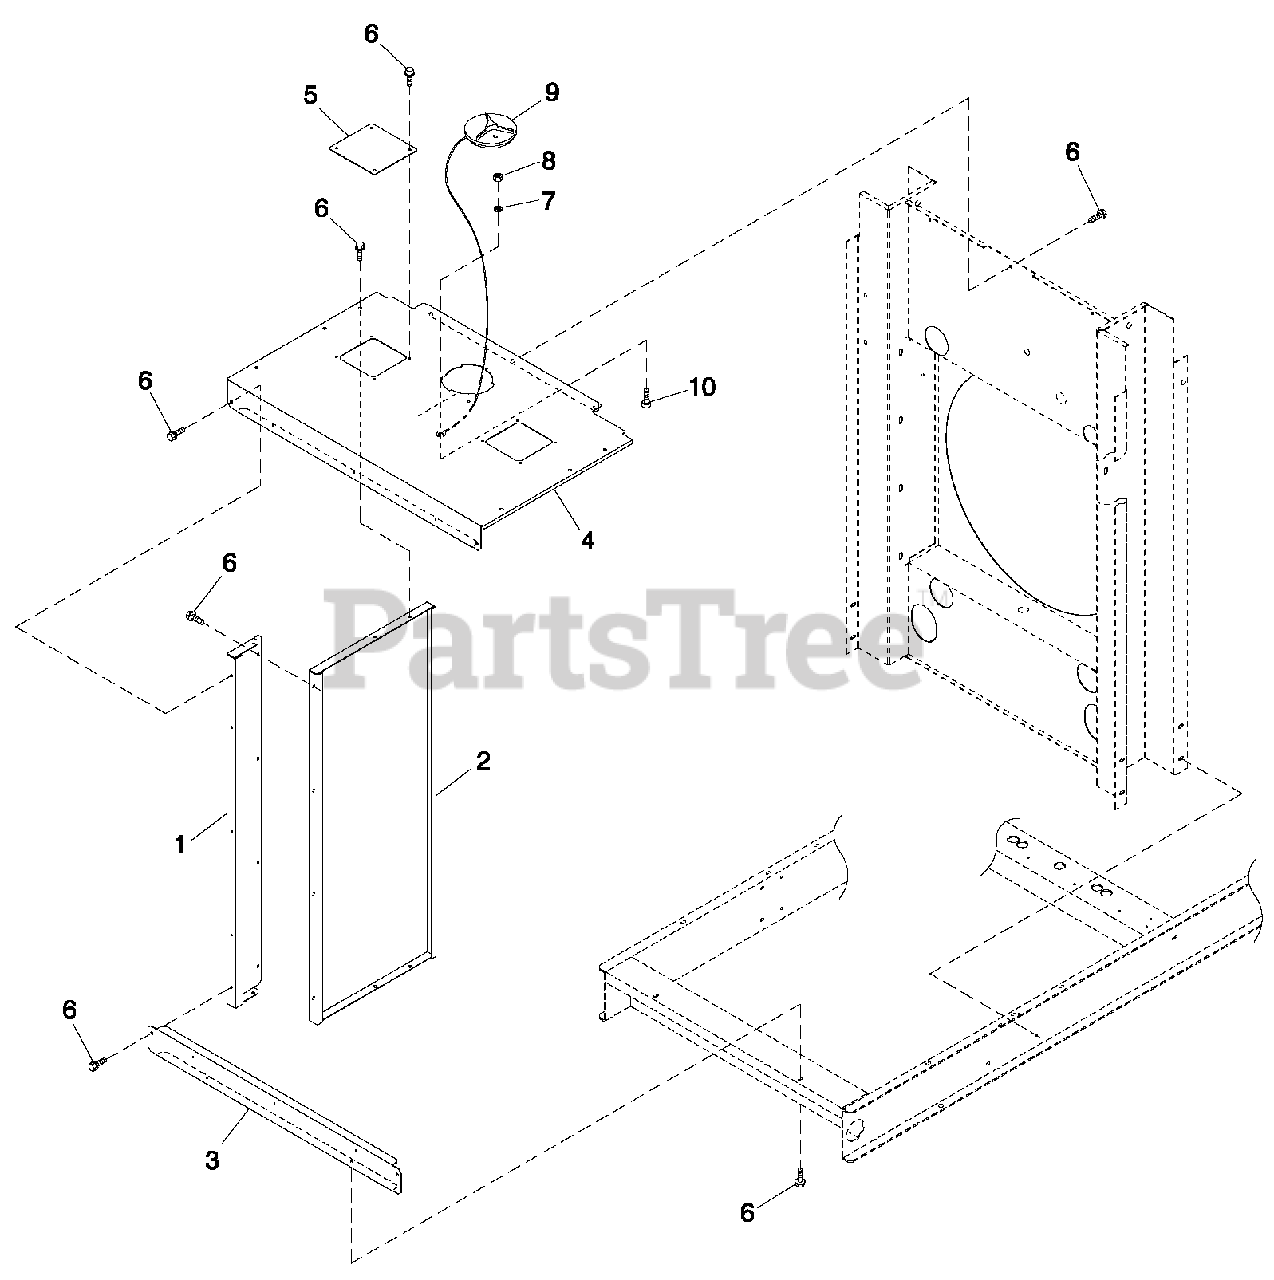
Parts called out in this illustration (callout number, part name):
1	PANEL C3 FRONT SIDES
2	PANEL C3 REAR SIDES
3	PANEL LOWER FRONT
4	PANEL C3 TOP
5	ACCESS COVER 160 X 170 GALV
6	SCREW THF M6-1 X 16 N WA Z/JS
7	WASHER LOCK M6-1/4
8	NUT HEX M6 X 1.0 G8 YEL CHR
9	ASSY ACCESS COVER
10	SCREW HHC M6-1.0X 16 G8.8
